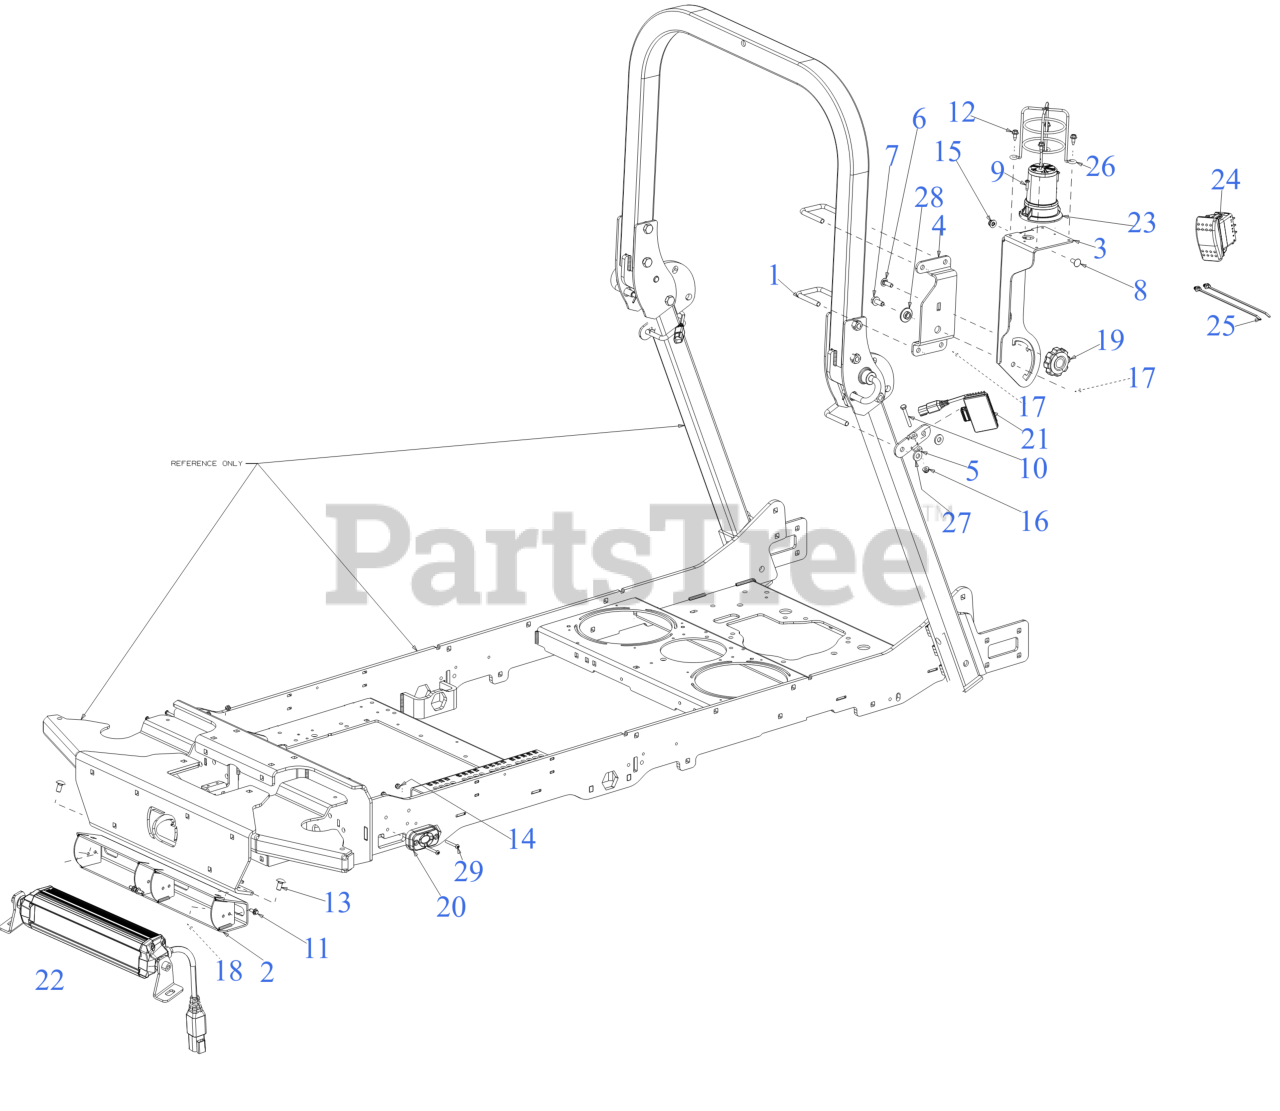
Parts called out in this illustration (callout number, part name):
1	U-BOLT, 3/8-16 X
2	HEADLIGHT BRACKET
3	PIVOT MOUNT BRACKET
4	FIXED MOUNT BRACKET
5	LIGHT MOUNT BRACKET
6	CARRIAGE BOLT 5/16-18 x 1.00
7	SCREW 3/8-16 x .875 GR5
8	CARRIAGE BOLT 5/16-18 x .75
9	SCREW (10-24X.75:PH:TAP:T25:GR5)
10	SCREW 1/4-20 x 2 GR5
11	SCREW M6-1 x .625
12	SCREW 1/4-20X.625
13	CARRIAGE BOLT 3/8-16 x .75
15	FLANGE LOCK NUT 5/16-18
16	FLANGE LOCK NUT
18	HEX LOCK NUT
19	KNOB-5/16-18
20	LED HEADLIGHT (300LM)
21	LED HEADLIGHT (400LM)
22	LED HEADLIGHT (2000LM)
23	LED BEACON LIGHT
24	ROCKER SWITCH
25	CABLE TIE
26	BEACON LIGHT COVER
27	FLAT WASHER
28	SHOULDER SPACER
